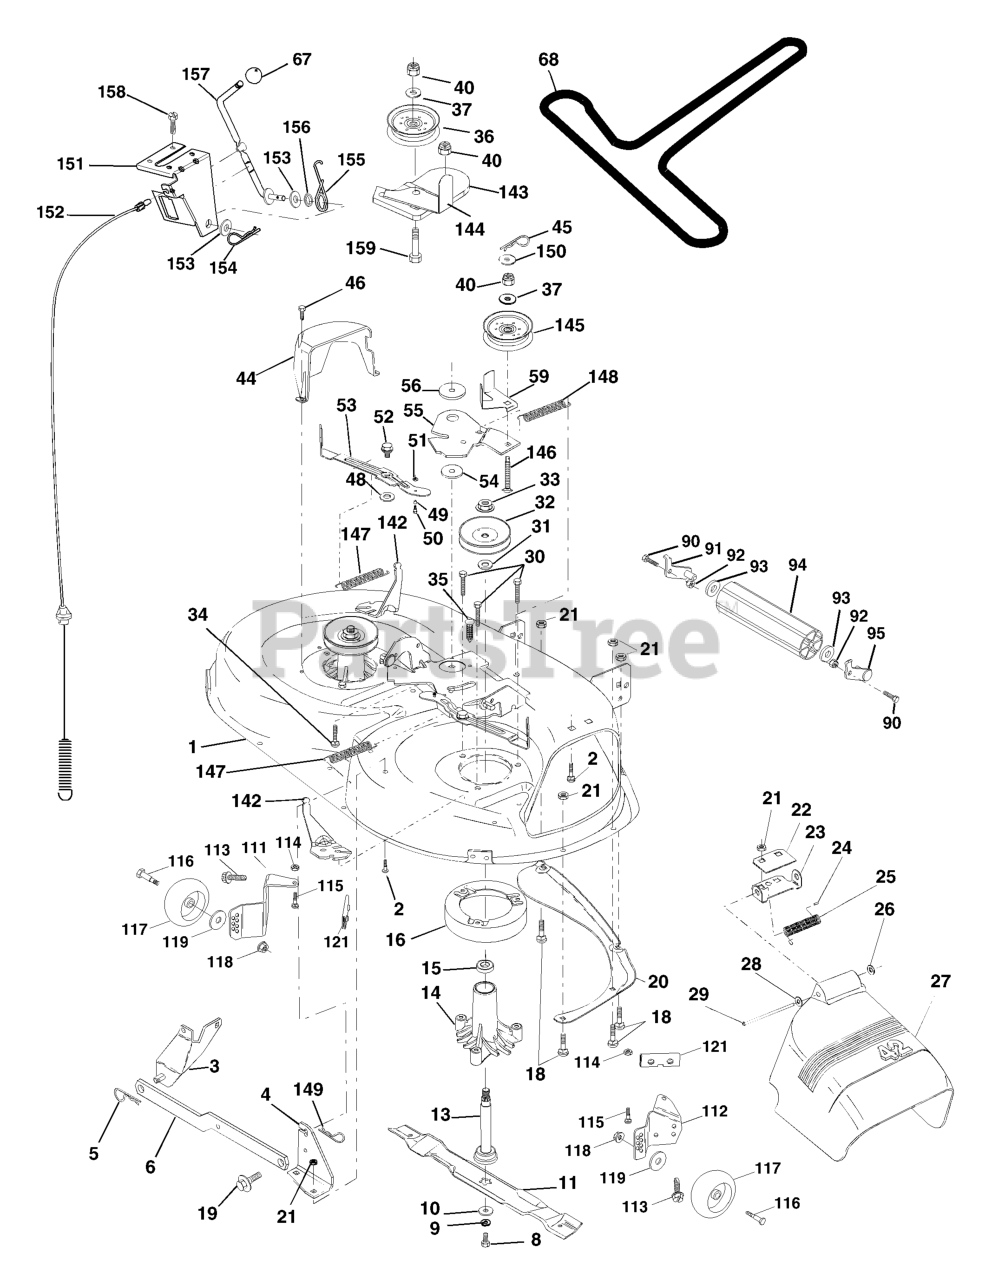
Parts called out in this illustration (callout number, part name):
1	42" DECK KIT
2	RP BOLT 5/16-18 X3/4 ZN/YEL GR
3	BRKT ASM SWAY BAR
4	BRACKET SWAY BAR 42" DECK
5	RETAINER-SPRNG RB
6	REAR SUSP ARM
8	BLADE BOLT
9	LOCKWASHER
10	WASHER.BLADE
11	Blade Mower 42"
13	SHAFT ASM VENT
14	HOUSING.MANDREL.VENTED (MACHD)
16	STRIPPER
18	BOLT
19	BOLT SHD 5/16-18
20	BAFFLE.VORTEX
21	LOCKNUT
22	STIFFENER BRACKET
23	DEFLECTOR BRACKET
24	CAP-SLEEVE LT
25	SPRING TORSION
26	NUT PUSH M
27	SHIELD DEFLECTOR
28	Washer 11/32 X 5/8 X 16 Ga
29	ROD.HINGE
30	SCREW THDROL ROLLING WASHER HD
31	WASHER
32	PULLEY/MANDREL
33	NUT
35	FASTENER.XMAS.TREE
36	FLAT IDLER PULLEY
37	WASHER
44	GUARD MANDREL LH BLACK
45	RETAINER M
46	SCREW.1/4-20X5/8
49	ROLLER ASM CAM FOLLOWER
52	BOLT.SHOULDER.5/16-18
53	ARM
54	HARDENED WASHER
55	ARM IDLER 42" MOWER LT/YT
56	SPACER.RETAINER.MOWER
59	GUARD, BELT
67	KNOB T (3/8 HOLE)
68	BELT V SECONDARY
90	BOLT
91	BRACKET LH (A)
92	NUT
93	Washer 17/32 x 7/8 x 16 Ga.
94	NOSE ROLLER
95	BRACKET RH (B)
111	BRACKET WHEEL GAUGE LH 42" DK
112	BRACKET WHEEL GAUGE RH 42" DK
113	Screw 5/16-18
114	NUT
115	BOLT.CARR.5/16-18X1/2
116	BOLT M
117	WHEEL.GAUGE.STANDARD
118	LOCKNUT
119	WASHER.5/16.FLAT.STE.STD.
121	BRACKET.EXTRUDED.GAGE.WHEEL
129	WASHER
130	BOLT
131	BOLT D
142	ARM SPRING BRAKE MOWER
143	BRACKET, ARM IDLER
144	DNO KEEPER.BELT.42".CLUTCH.CBL
145	PULLEY
146	BOLT, CARRIAGE IDLER BLACK
147	SPRING EXTENSION
148	IDLER RETURN SPRING
149	KIT CYLINDER #70331
150	WASHER PM
151	BRACKET.CLUTCH.CABLE
152	CLUTCH CABLE 42"
153	WASHER FLAT 3/8"
154	SPRING RETAINER
155	SPRING RETENTION LEVER
156	SPACER.CLUTCH.CABLE
157	ROD CLUTCH CABLE 3/8"
158	SCREW LT
159	BOLT
